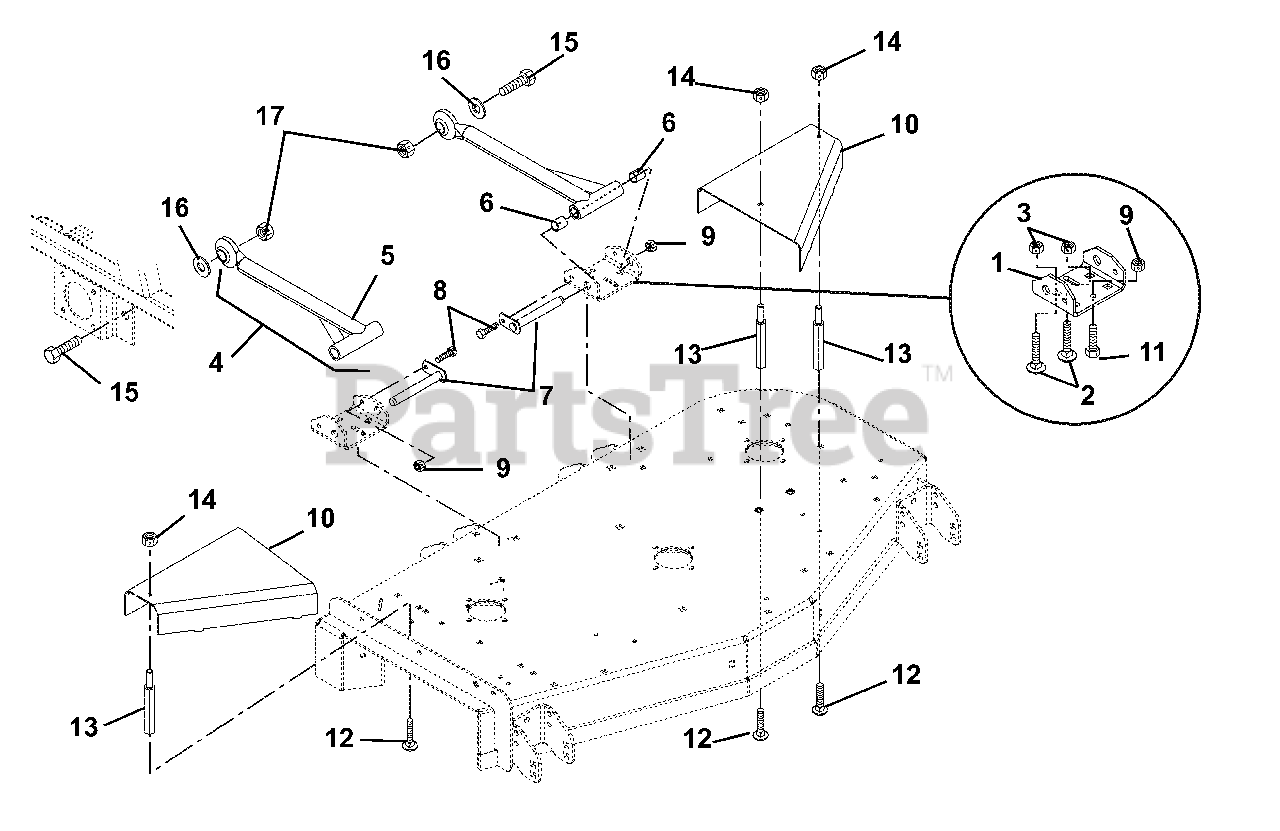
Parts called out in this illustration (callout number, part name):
1	Bracket, Mower Mounting (Rear)
2	Bolt, Round Head Square Neck .50-13 x .75 Grade 5
3	Nut, Locking Center Jam .50-13
4	Assembly, Mower Mounting Arm
5	Weldment, Mower Mounting Arm
6	Bearing .75 x .875 x 1.00
7	Weldment, Mower Mounting Pin
8	Bolt, Hex .38-16 x 1.00 Grade 5
9	Nut, Locking Top Flange .38-16
10	Guard, Pulley Left Hand (073, 075, 318, 319)
10	Guard, Pulley Right Hand (073, 075, 318, 319)
10	Guard, Right Hand Pulley (074, 076)
10	Guard, Left Hand Pulley (074, 076)
11	Bolt, Round Head Square Neck .38-16 x .75 Grade 5
12	Bolt, Round Head Square Neck .31-18 x .75
13	Standoff 2.75 x 5/16-18
14	Nut, Locking Top Flange .31-18
15	Bolt, Hex .875-9 x 2.75 Grade 5
16	Washer, Flat Steel .875 x 1.50 x .120
17	Nut, Locking Center .875-9
